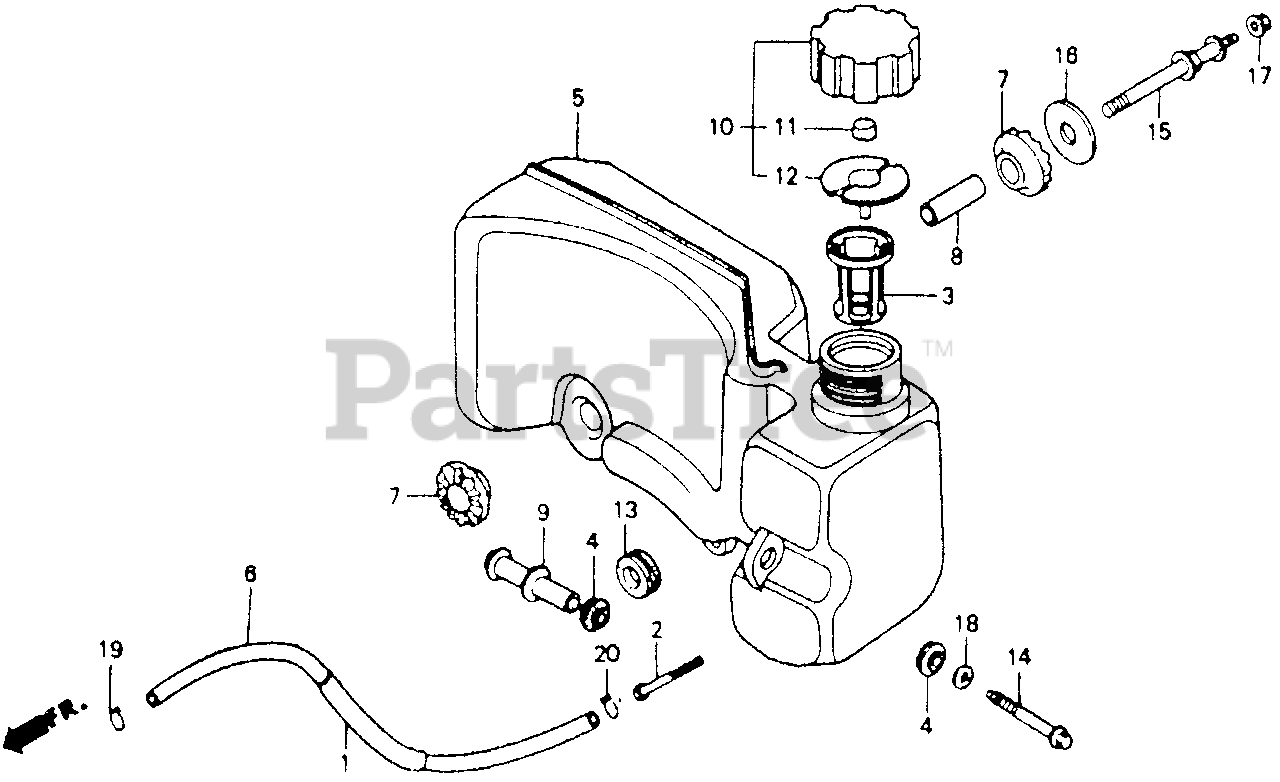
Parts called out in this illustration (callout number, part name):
1	RUBBER, SUPPORTER (107MM)
2	FILTER, FUEL
3	GAUGE, FUEL LEVEL (NOT AVAILABLE)
4	RUBBER, TANK SETTING
5	TANK, FUEL
6	TUBE, FUEL
7	RUBBER B, TANK MOUNTING
8	COLLAR, TANK SETTING
9	COLLAR, TANK
10	CAP ASSY., FUEL TANK
11	SPONGE, FUEL CAP BREATHER
12	GASKET, FUEL CAP
13	CUSHION, RR. FENDER
14	BOLT, FLANGE (6X50)
15	BOLT, TANK STAY
16	WASHER, TANK MOUNTING
17	NUT, FLANGE (6MM)
18	WASHER, PLAIN (6MM)
19	CLIP, TUBE (B8)
20	CLIP, TUBE (C11)
